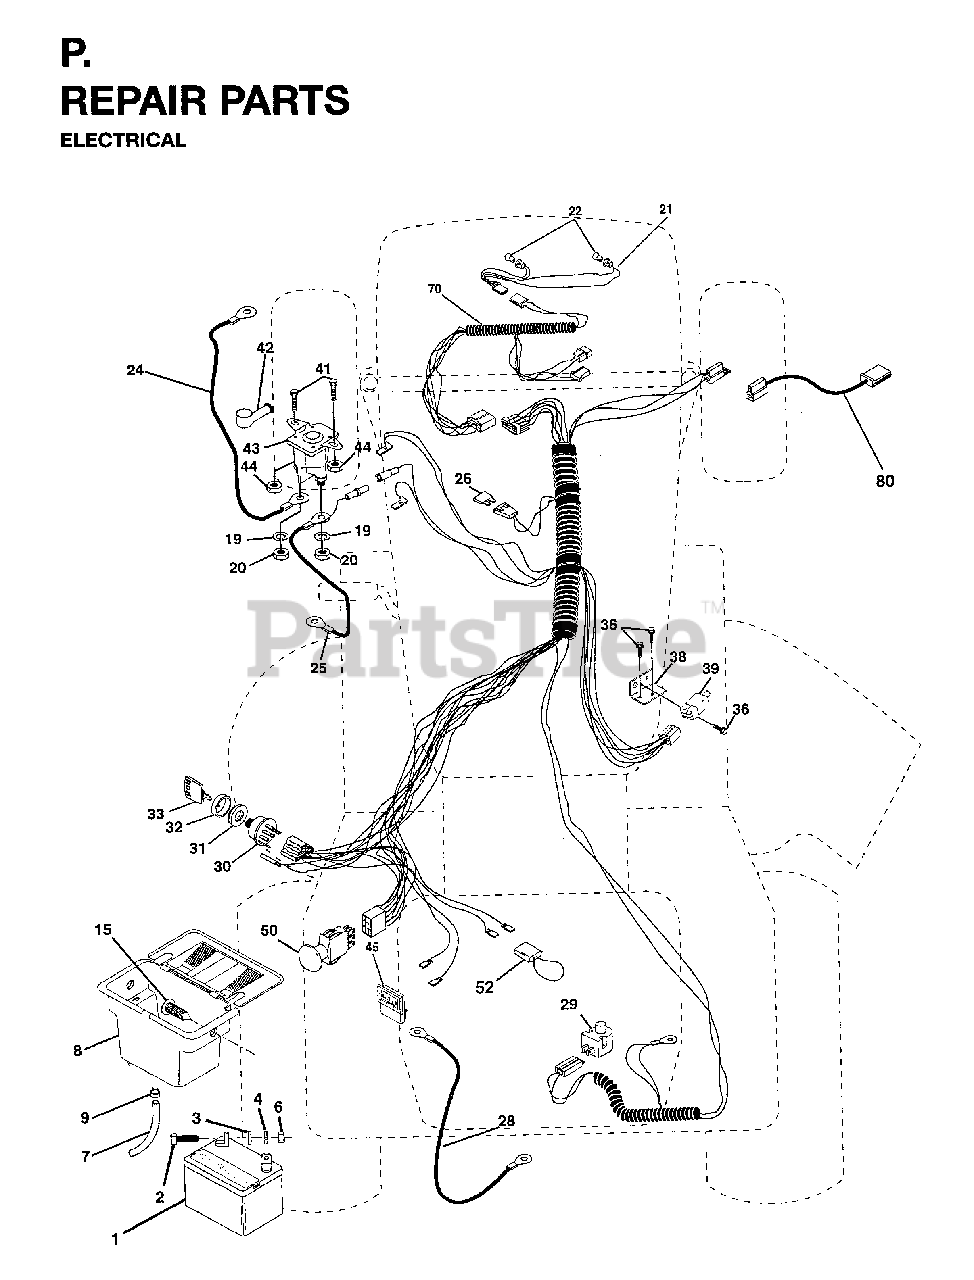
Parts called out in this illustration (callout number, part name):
1	BATTERY
4	LOCKWASHER
6	NUT
7	TUBE BATTERY DRAIN
8	BATTERY CASE
9	HOSE CLAMP T
15	FASTERER SNAP-IN
19	LOCKWASHER
20	NUT
21	HARNESS ASM HDLIG
22	LIGHTBULB
24	BATTERY CABLE
25	CABLE BATTERY
28	CABLE T
29	SWITCH SEAT
30	SWITCH.IGNITION.4.POSITION
31	NUT IGNITION
32	COVER SWITCH KEY
33	KEY SET
38	SWITCH BRACKET
39	SWITCH INTERLOCKT
41	BOLT
42	TERMINAL COVER
43	KIT SOLENOID .95
44	NUT.CROWNLOCK.1/4
50	SWITCH-PTO
52	WIRE PROTECTION LOOP
70	HARNESS ENGINE
80	HARNESS, CLUTCH
